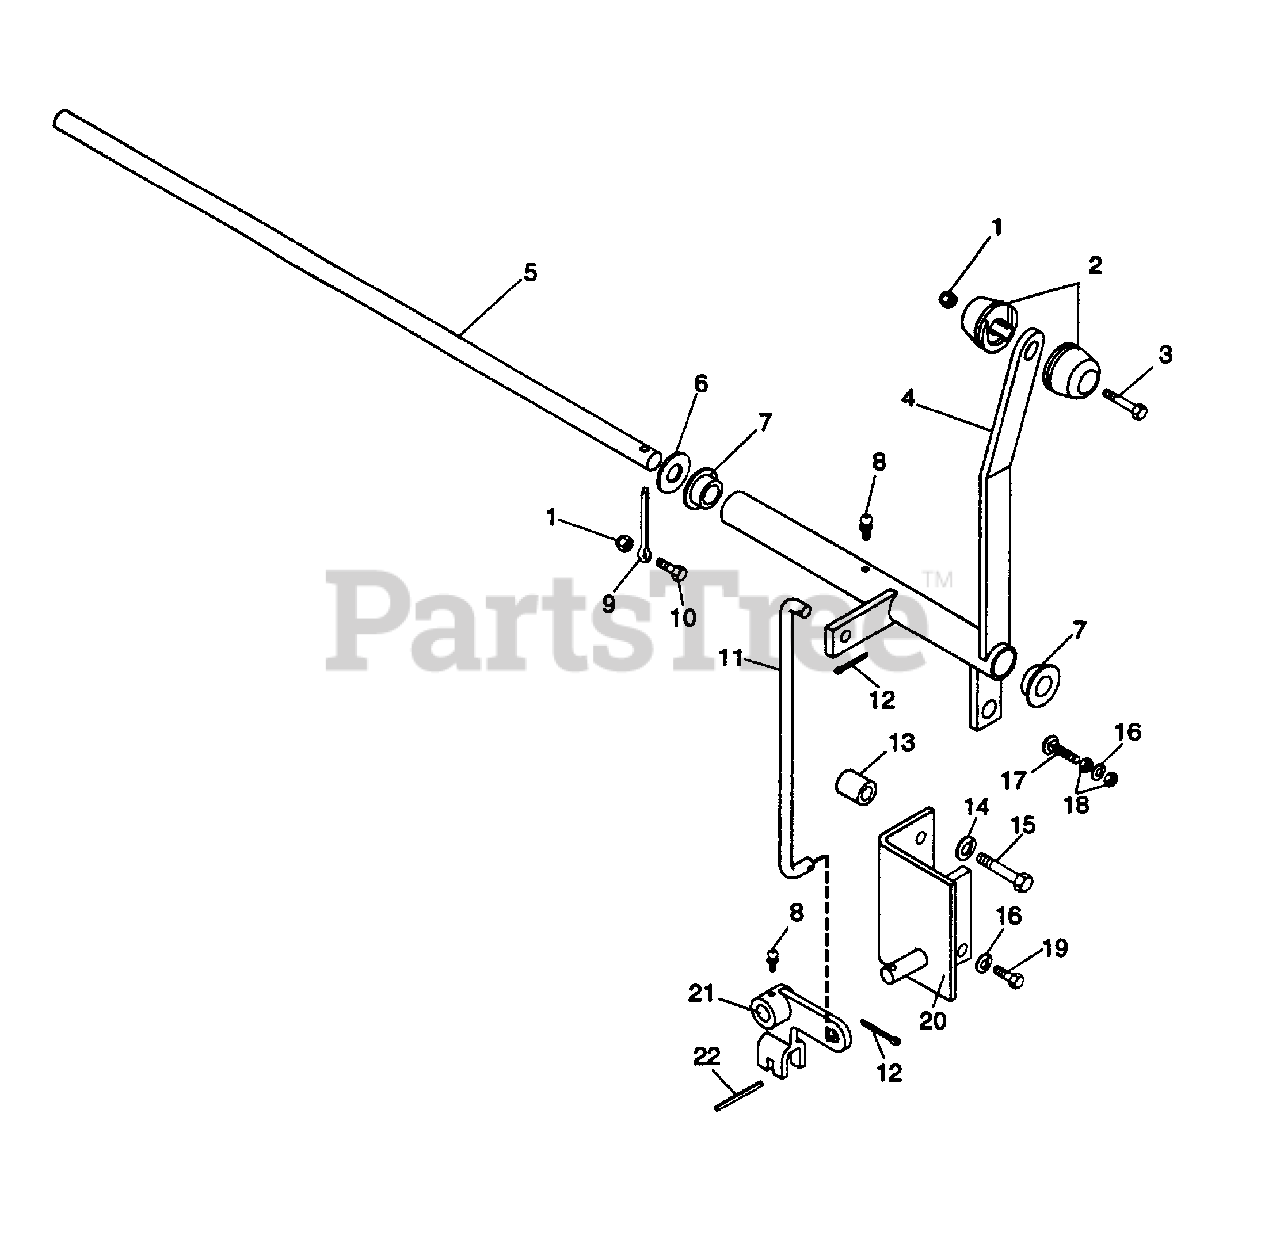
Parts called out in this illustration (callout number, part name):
1	NUT-LK-NYL .250-20 PL
2	KNOB, CONTROL
3	BLT-HEX .25-20 X 1.50 PL GR 5
4	CNTRL, HI-LO
5	SHFT, CONTROL
6	WSHR-FL-STL .531 X 1.062 X .095
7	BUSH., F .515 X 1.00 X .745 NY
8	FTG, LUBE; .25-28 SELF-THREAD
9	PIN-COTR .250 X 2.00
10	BLT-HEX .25-20 X .875
11	ROD, HI-LO
12	PIN-COTR .09 X .75 PL
13	BSHG-SLV .407 X .625 X .750 PL
14	WSHR-LOCK .313 X .078 PL
15	BLT-HEX .31-18 X 2.00 PL GR 5
16	WSHR-LOCK .250 REG.
17	SCR-MCH .25-20 X 1.25 HSHD
18	NUT-HEX .250-20 ZC
19	BLT-HEX .25-20 X .75 PL GR 5
20	WLDMT, HI-LO BRACKET
21	LEVER, HI-LO
22	PIN, SPRING .250 X 1.000
